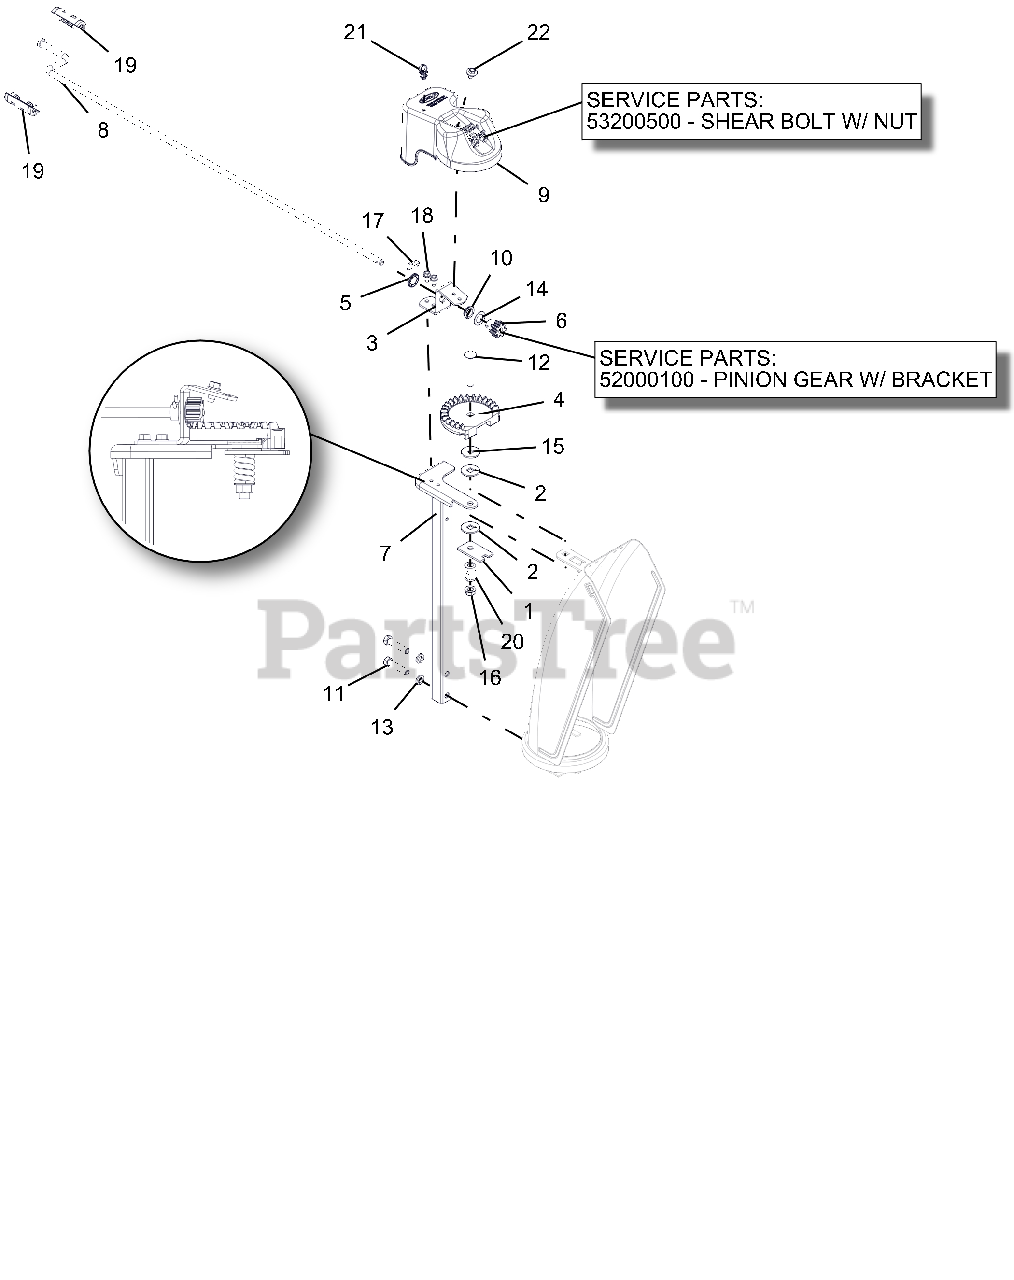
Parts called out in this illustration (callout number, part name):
1	PLATE, FRICTION
2	FRICTION WASHER
3	BRACKET, PINION GEAR
4	CHUTE GEAR
5	PUSHNUT .625
6	PINION GEAR - CHUTE
6	PINION GEAR W/BRACKET
7	CHUTE PEDESTAL, TALL COMPACT
8	ROD, CHUTE CRANK, COMP&SNOTEK
9	GEAR COVER ASSY SM SHEAR BOLT
9	SHEAR BOLT WITH NUT
10	BUSHING, POLYLINER-.63 SNAPIN
11	@BLT-HEX .38-16X1.75 GR5 YWZC
12	@BLT-RDHDSQNK .38-16X2.50 G5YZ
13	@WSHR-LK .38X.094 REG YWZC
14	WSHR-THRST .625 X 1.0 X .03
15	@WSHR-FL-STL .406X1.25X.10 ZC
16	@NUT-LK-TOP-FLG .38-16 YWZC
17	PIN, SPRING CLIP
18	SCR-TAP .25-20X.50 HWH TR YWZ
19	KNOB, CHUTE CRANK - SNAP GRAY
20	SG-COMP .187X.56X1.62
21	CLIP, CABLE GUIDE
22	SCR-TAP .25-20X.50 LGHWH TR YZ
